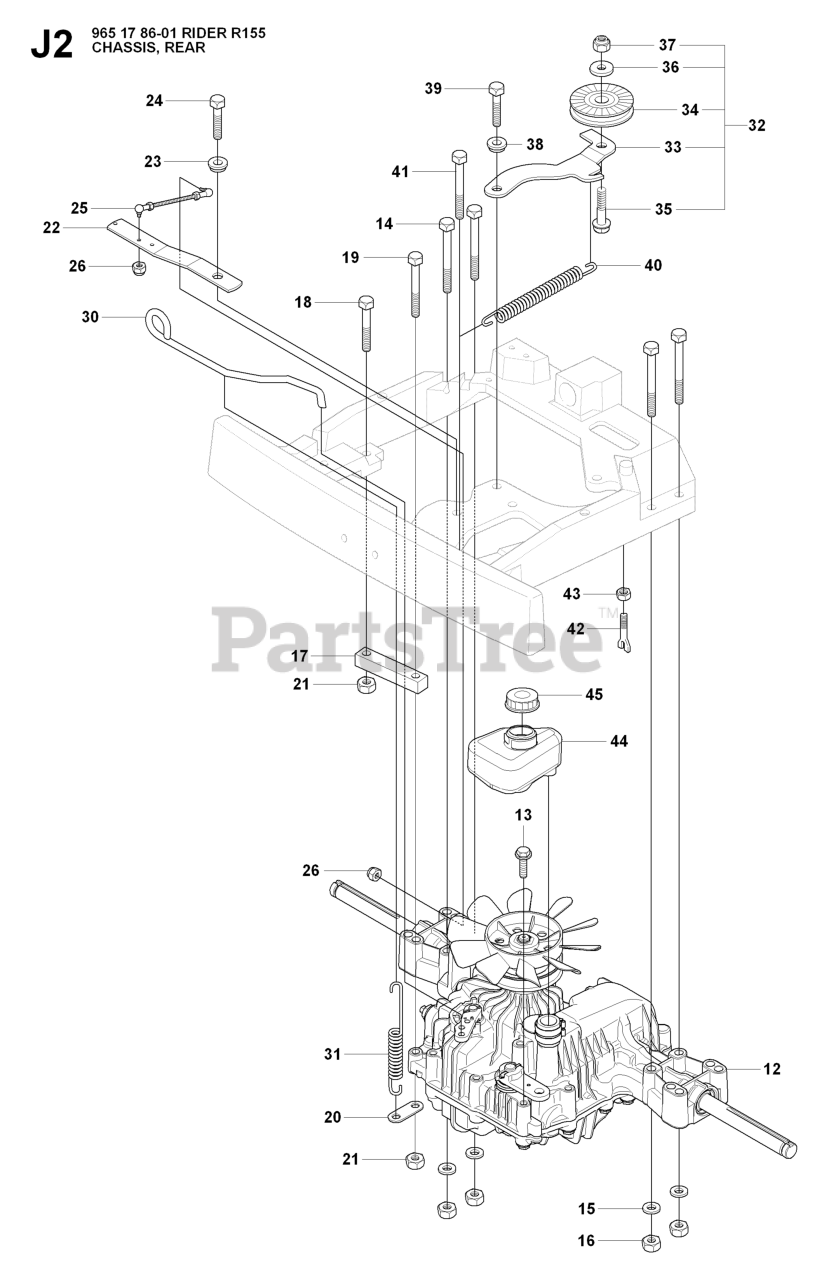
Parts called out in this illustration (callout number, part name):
12	HYDROSTAT 7A646024070
15	WASHER BRB 8.4X17
16	NUT
21	NUT
23	WASHER
24	SCREW 8X20
26	LOCKNUT M5
33	TENSIONER
35	SCREW
37	LOCKNUT M8
38	WASHER
39	SCREW 8X20
43	NUT
45	TANK CAP
